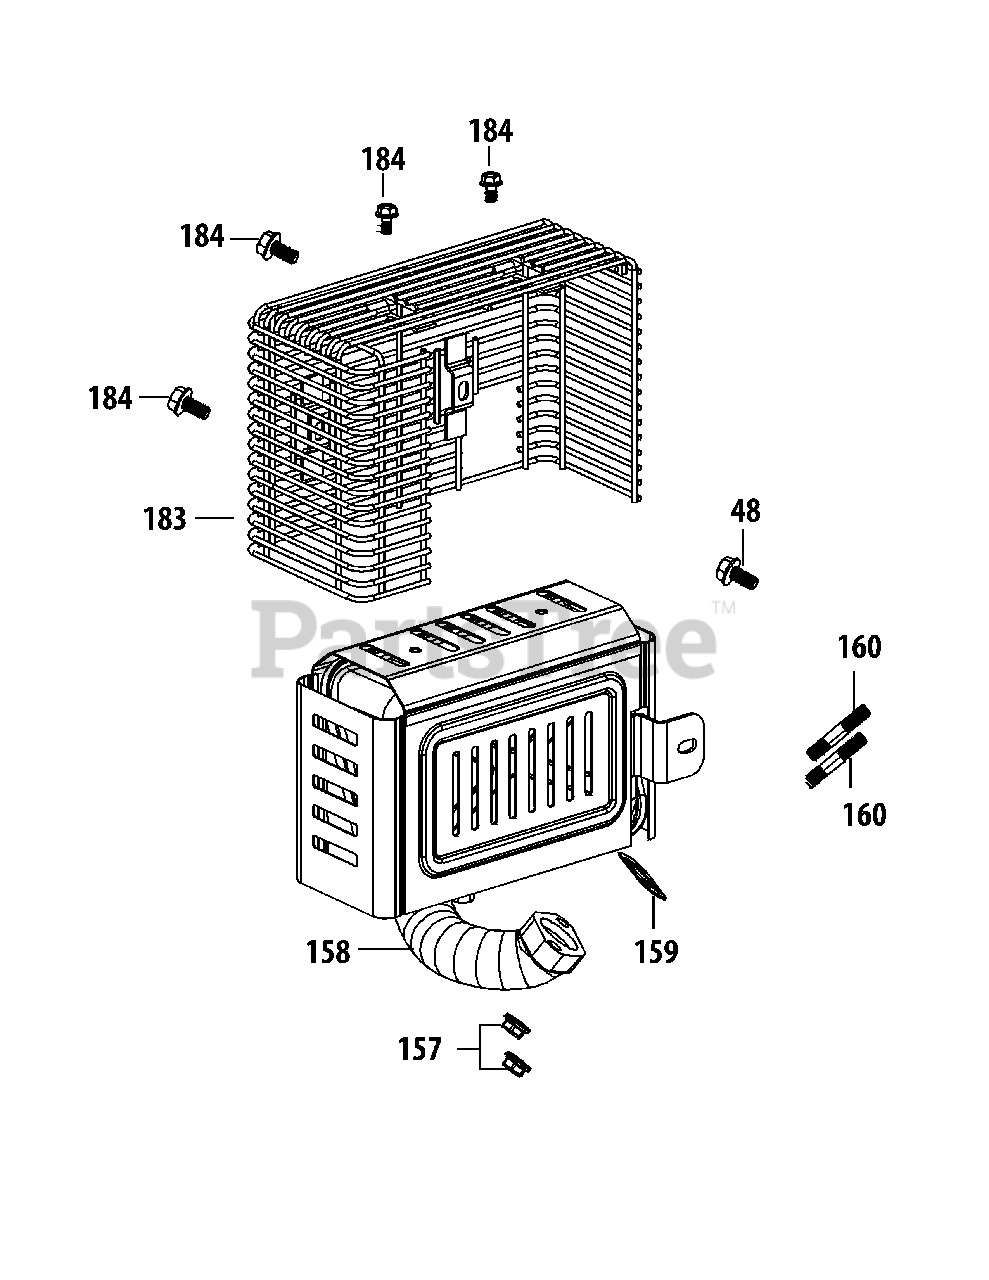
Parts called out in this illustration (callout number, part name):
48	Bolt M6×14
158	Muffler Assembly
159	Exhaust Pipe Gasket
160	Muff Stud M8×47
160	Muffler Stud Assembly
183	Wire Mesh Shield
184	Bolt M6×12
